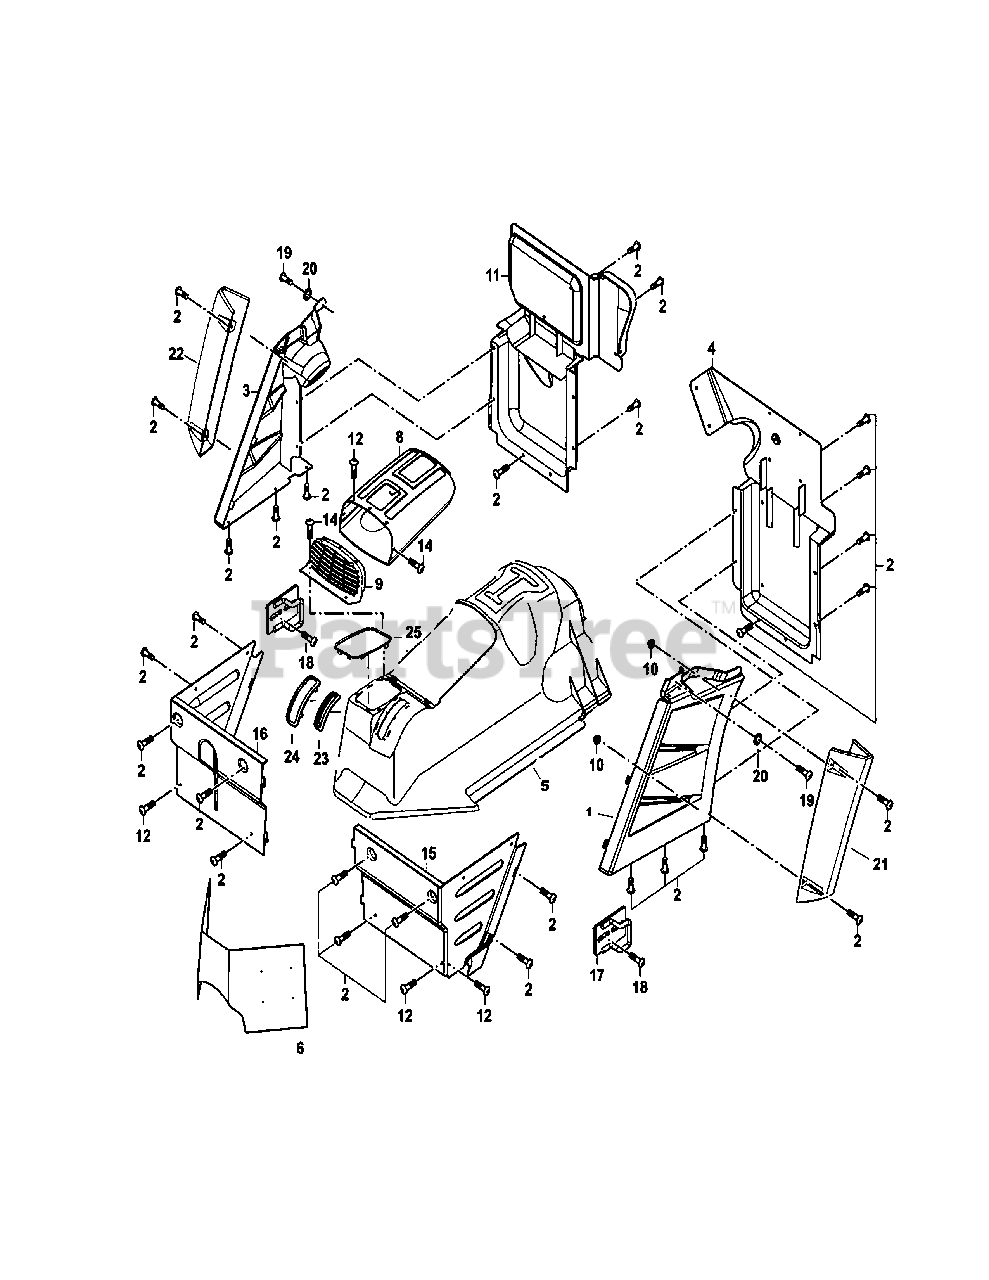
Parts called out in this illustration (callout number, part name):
1	Left Seat Board
2	Cross large plate head screw M6x16
3	Right Seat Board
4	Rear Left Board, Seat
5	Engine Cover Board
6	Insulation Paper VI
8	Primary Air Filter Box
9	Primary Air Filter Cap
10	Hexagon Flange Self-Lock Nuts M6
11	Rear Right Board, Seat
12	Expansion Bolt(Plastic)
14	Cross Large Plate Head Screw M5x16
15	Front Left Board, Seat
16	Front Right Board, Seat
17	Door Locker
18	Hexagon Flange Bolt M6x16
19	Cross Large Plate Head Screw M6x12
20	Nut Clip M6
21	Left side board decorative plate
22	Right side board decorative plate
23	Dust P. Cover
24	Parking Decoration Cover
25	Gear Shift Decoration Cover
